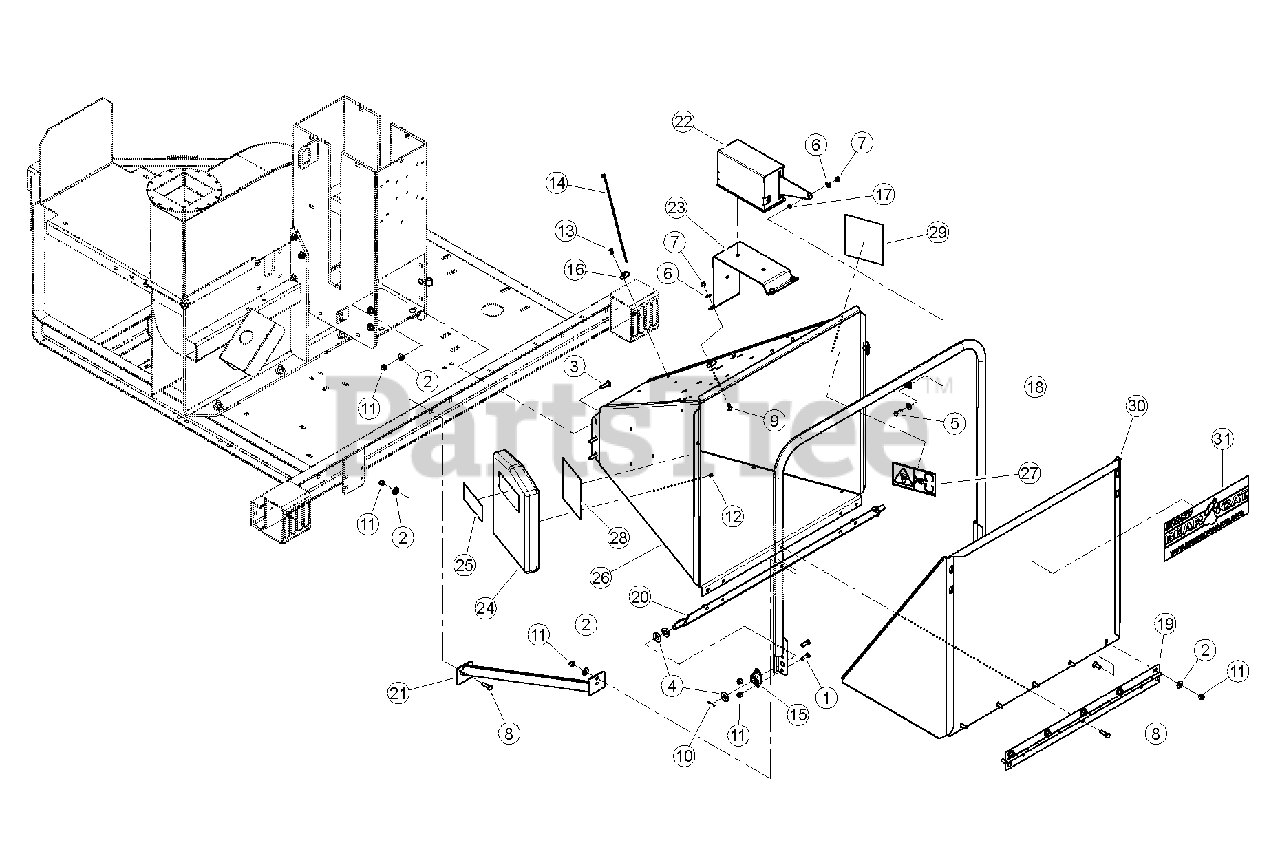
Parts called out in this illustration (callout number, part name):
1	BOLT, 3/8 X 1 HEX HD GR5 ZP
2	WASHER, 3/8 FLAT ZP
3	BOLT, 3/8 X 1-1/2 CRG GR5 ZP
4	WASHER, 5/8 SAE FLAT ZP
5	BOLT, 5/16 X 1 HHCS GR5 NC ZP
6	WASHER, 5/16 FLAT ZP
7	NUT, 5/16 NE NYLOCK ZP
8	BOLT, 3/8 X 1-1/4 HEX HD GR5 ZP
9	BOLT, 5/16 X 3/4 CRG GR5 NC ZP
10	PIN, 1/8 X 1.00 ZP COTTER
11	NUT, 3/8 NE NYLOCK ZP
12	RIVET, AL BLIND 1/4 X 1/2 DOME HEAD
13	RIVET, AL BLIND 1/4 X 3/4 DOME HEAD
14	STRAP, 11 IN. BLACK TIE
15	BEARING, SIDE FLNG MOUNT 5/8"
16	CLAMP, CABLE MOUNT
17	SPACER, IDLER PIVOT
18	WELDMENT, CONTROL ARM
19	HINGE, EXTENSION TRAY
20	WELDMENT, CONTROL PIVOT
21	WELDMENT, CHUTE SUPPORT
22	ASSEMBLY, SWITCH BOX
23	MOUNT, SWITCH BOX
24	ASSEMBLY, MANUAL CONTAINER SERVICE PART
25	DECAL, MUTILINGUAL MANUAL
26	ASSEMBLY, BIG CHIPPER CHUTE SERVICE PART
27	DECAL, BLADE DANGER ISO
28	DECAL, FEED POSITION
29	DECAL, FEED POSITION
30	ASSEMBLY, CHUTE EXTENSION TRAY SERVICE PART
31	DECAL, BEARCAT WEB
